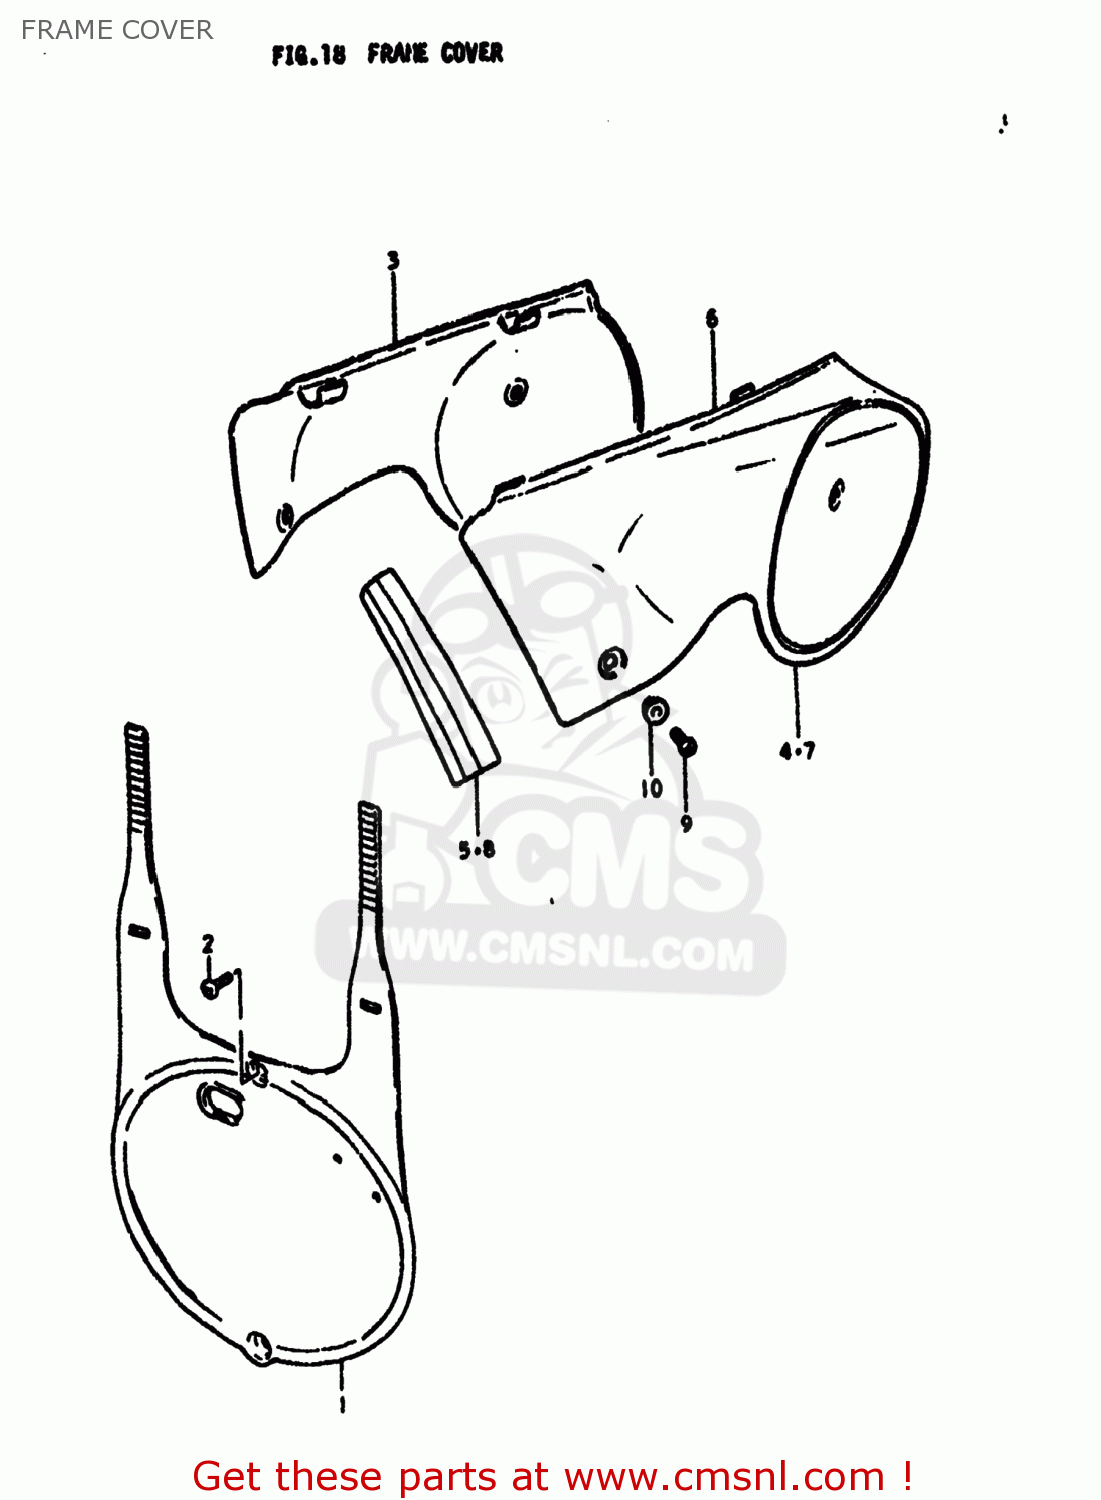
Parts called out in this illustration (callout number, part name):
1	PLATE,FR NUMBER
2	(5X20) CROSS SCREW
3	COVER,FRAME,RIGHT
4	TAPE,FRAME COVER
6	COVER,FRAME,L(YELLOW)
7	TAPE,FRAME COVER
8	LABEL,FRAME COVER
9	SCREW 6X12
10	SPACER
